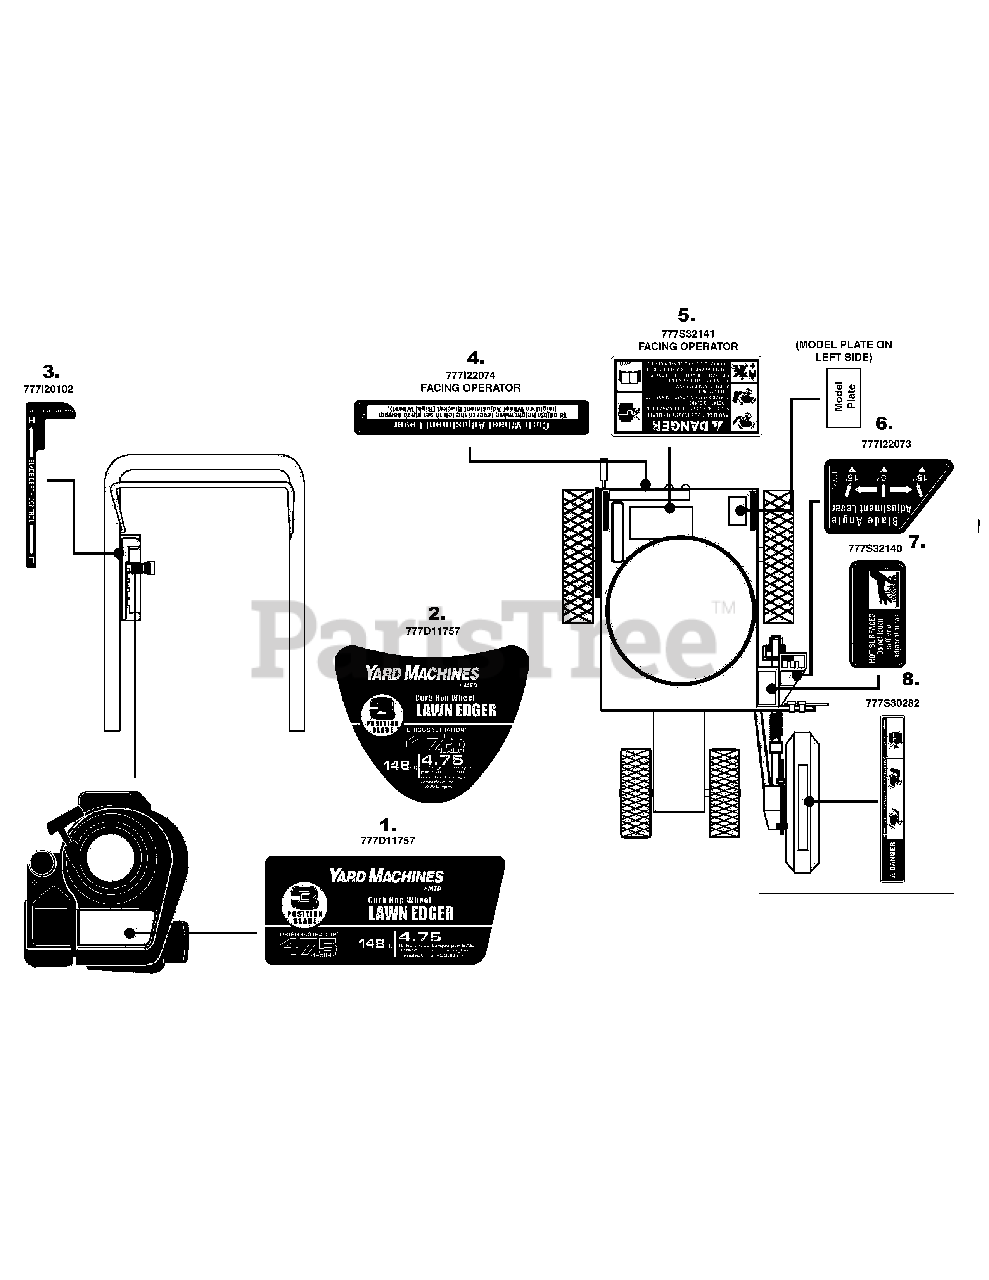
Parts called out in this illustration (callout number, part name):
1	LABEL-EDGER SHROUD YARD MACHINE
2	LABEL-EDGER SHROUD YARD MACHINE
3	LABEL DEPTH CNTRL
4	LABEL-FRAME REAR
5	LABEL-FRAME REAR
6	LABEL-FRAME LH
7	LABEL-MUFFLER
8	LABEL-BLADE COVER
